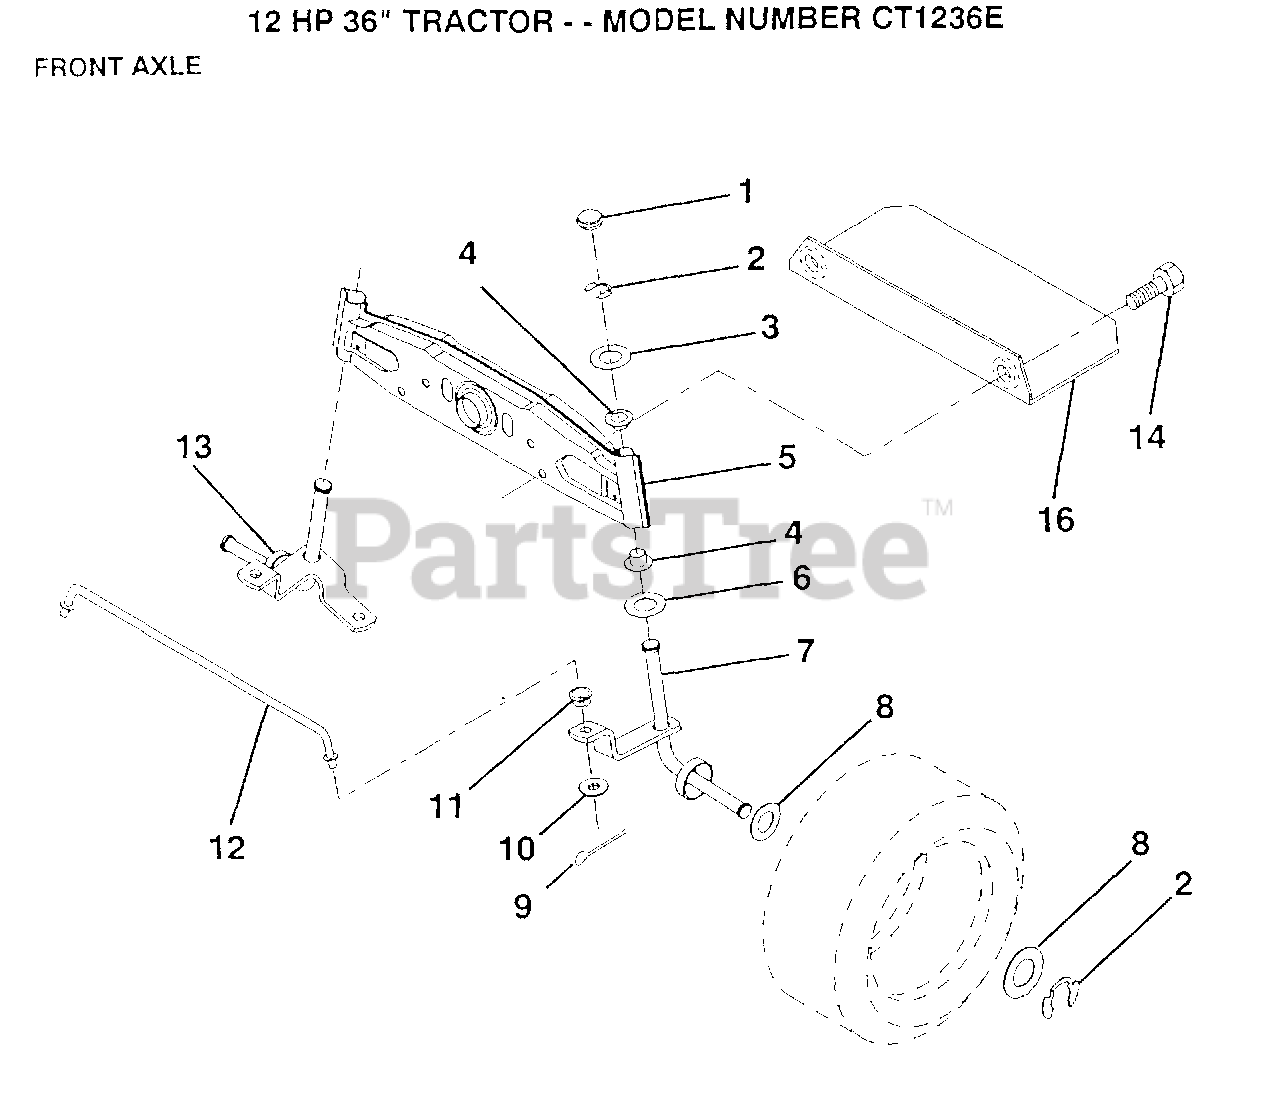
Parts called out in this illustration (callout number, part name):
1	CAP
2	RING
3	WASHER
4	NYLINER
5	AXLE FRONT
6	WASHER .T
7	SPINDLE RH
8	WASHER
9	COTTER PIN
10	WASHER
11	BUSHING.DRAGLINK
12	ROD TIE
13	SPINDLE LH
14	SCREW LT
16	HEAT SHIELD
